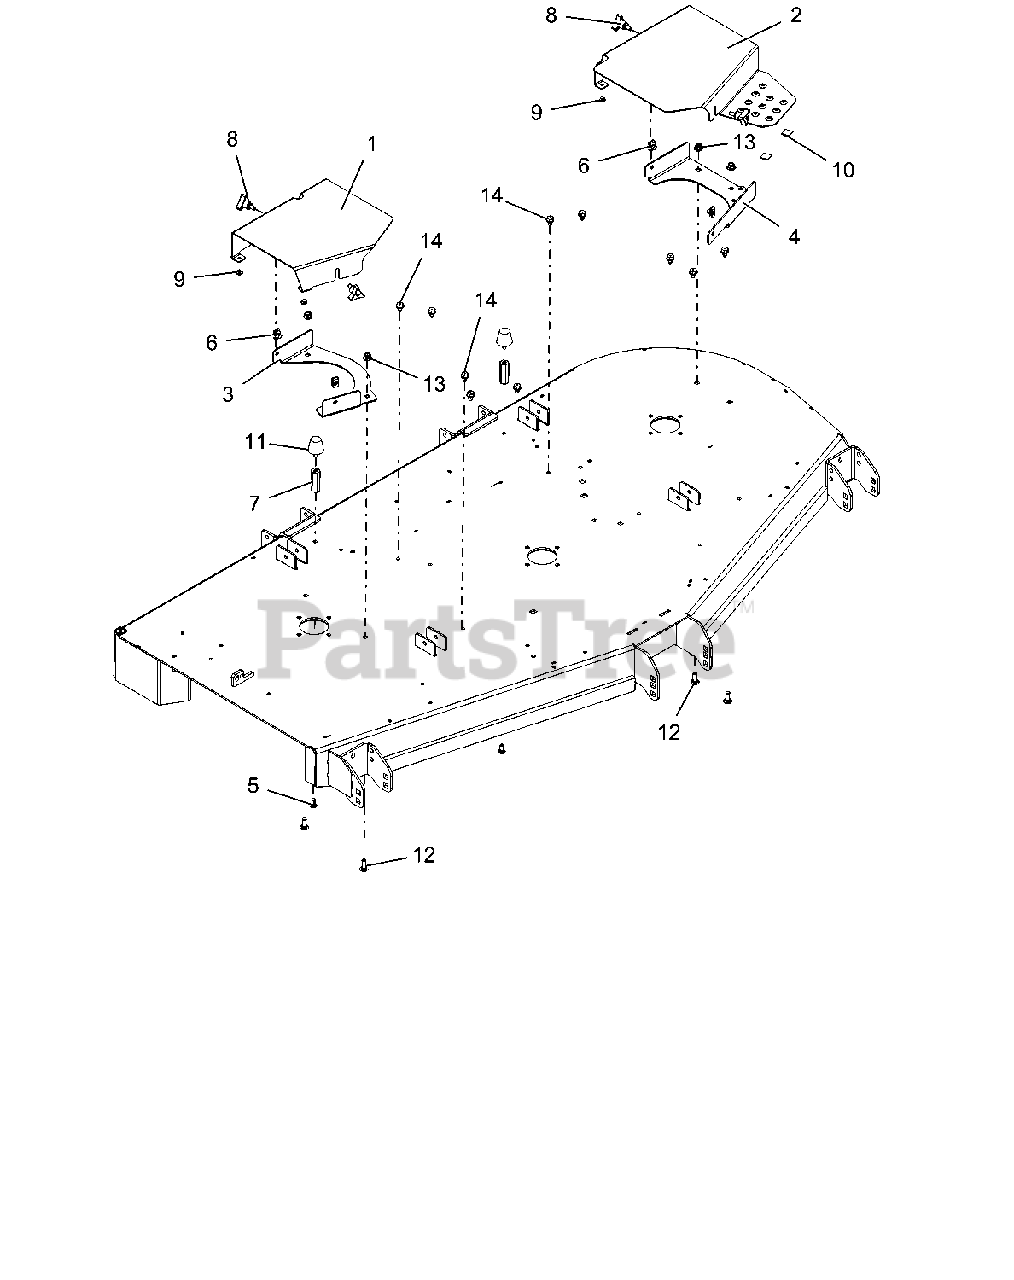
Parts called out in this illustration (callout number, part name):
1	GUARD, RH PT 400/200 BELT (RED)
2	GUARD, LH PT400/200 BELT
3	BRKT, BELT GUARD RH MOUNTING (RED)
4	BRKT, BELT GUARD LH (RED)
5	BLT, RDHDSQNK .31-18X.75 LOCTITE
6	NUT-CLIP RETAINER 5/16-18X.56
7	NUT, .31-18 X 2.25 LG COUPLING
8	KNOB, WING STUD .312-18X.75
9	BUMPER GROMMET .125 X .25 REV
11	BUMPER, RUBBER CONE STUD MOUNT
12	BLT-RDHDSQNK .38-16X1.00 G5 YWZC
13	NUT-LK-NYL-FLG .38-16 YWZC
14	SCR-TAP .38-16X.50 HWH TR YWZ
